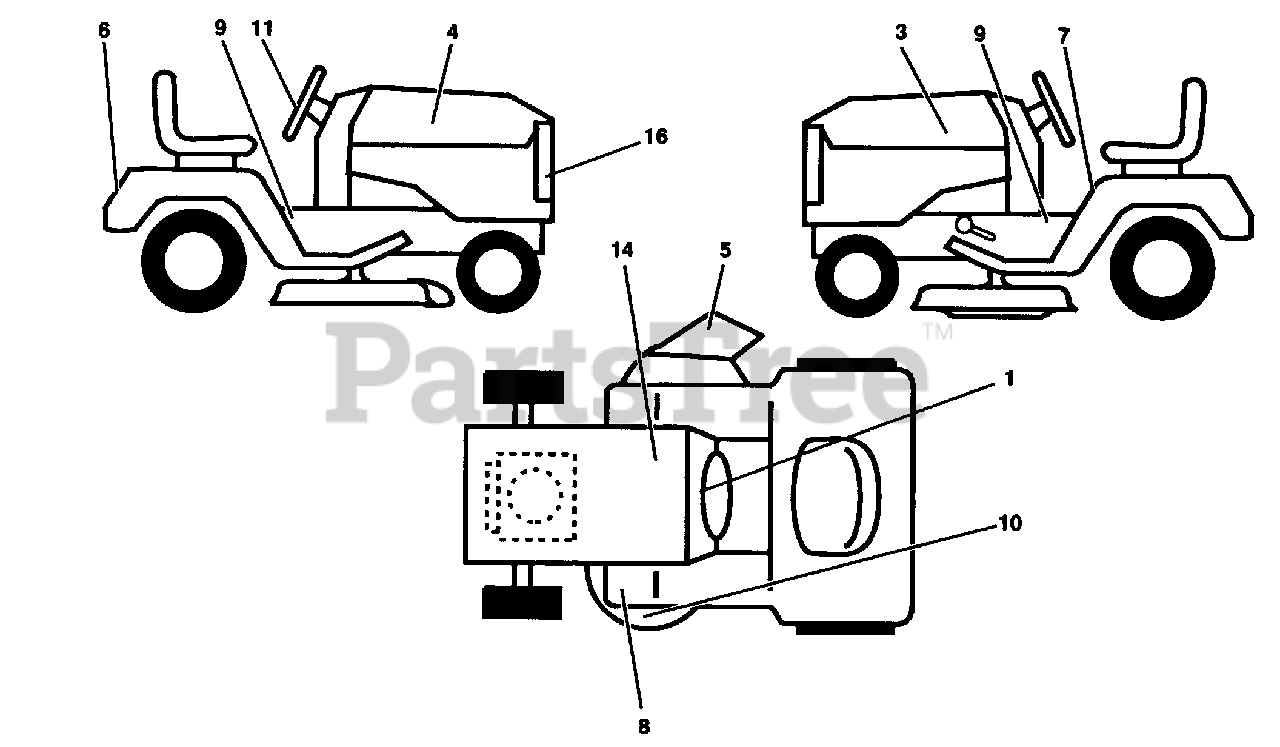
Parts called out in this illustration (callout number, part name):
1	Decal, Instruction Engine (AYP part number)
3	Decal, Hood Stripe L.H. (AYP part number)
4	Decal, Hood Stripe R.H. (AYP part number)
5	Decal, Danger, Deflector (English/French) (AYP part number)
6	Decal, Fender/Grill (AYP part number)
7	Decal, Caution (English/French) (AYP part number)
8	Decal, Clutch/Brake (English/French) (AYP part number)
9	Decal, Chassis (AYP part number)
10	Decal, Rotating Blades (AYP part number)
11	Decal, Steering Wheel Insert Manual Owner's (AYP part number)
14	Decal, Caution, Battery (French/German) (AYP part number)
16	Decal, Grill
